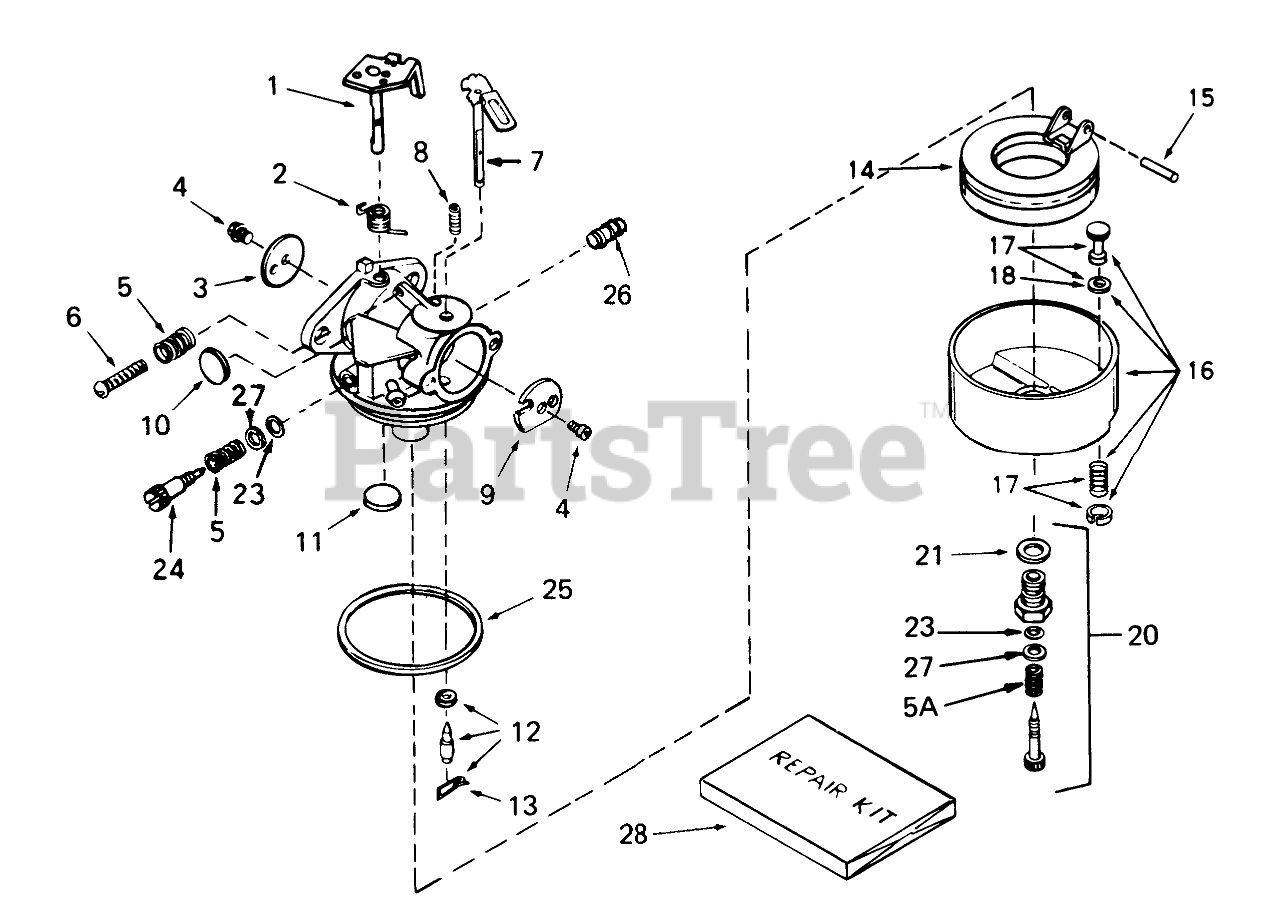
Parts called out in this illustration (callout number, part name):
1	Throttle Shaft and Lever ASM
2	Spring-Return, Throttle
3	Shutter-Throttle
4	Screw-Shutter
5	Spring-Tension
6	Screw-Throttle Crack Screw / Idle Speed
7	Choke Shaft and Lever ASM
8	Spring-Positioning, Choke
9	Shutter-Choke
10	Plug-Welch, Idle Mixture Well
11	Plug-Welch, Atmospheric Vent
12	Inlet Needle, Seat & Clip Assy. (Incl. Ref. #13)
13	Clip-Spring
14	Float
15	Shaft-Float
16	Float Bowl Assembly (Incl. Ref. #17 & 18)
17	Drain Assembly (Incl. Ref. #18)
18	Gasket-Plunger, Drain
20	Adjustment Screw Assy. (Incl. Ref. #5A, 21, 23 & 27)
21	Washer-Bowl Nut
23	"O"Ring
24	Screw-Idle Mix
25	O Ring-Bowl, Float
26	Fitting-Fuel
28	Kit-Repair
